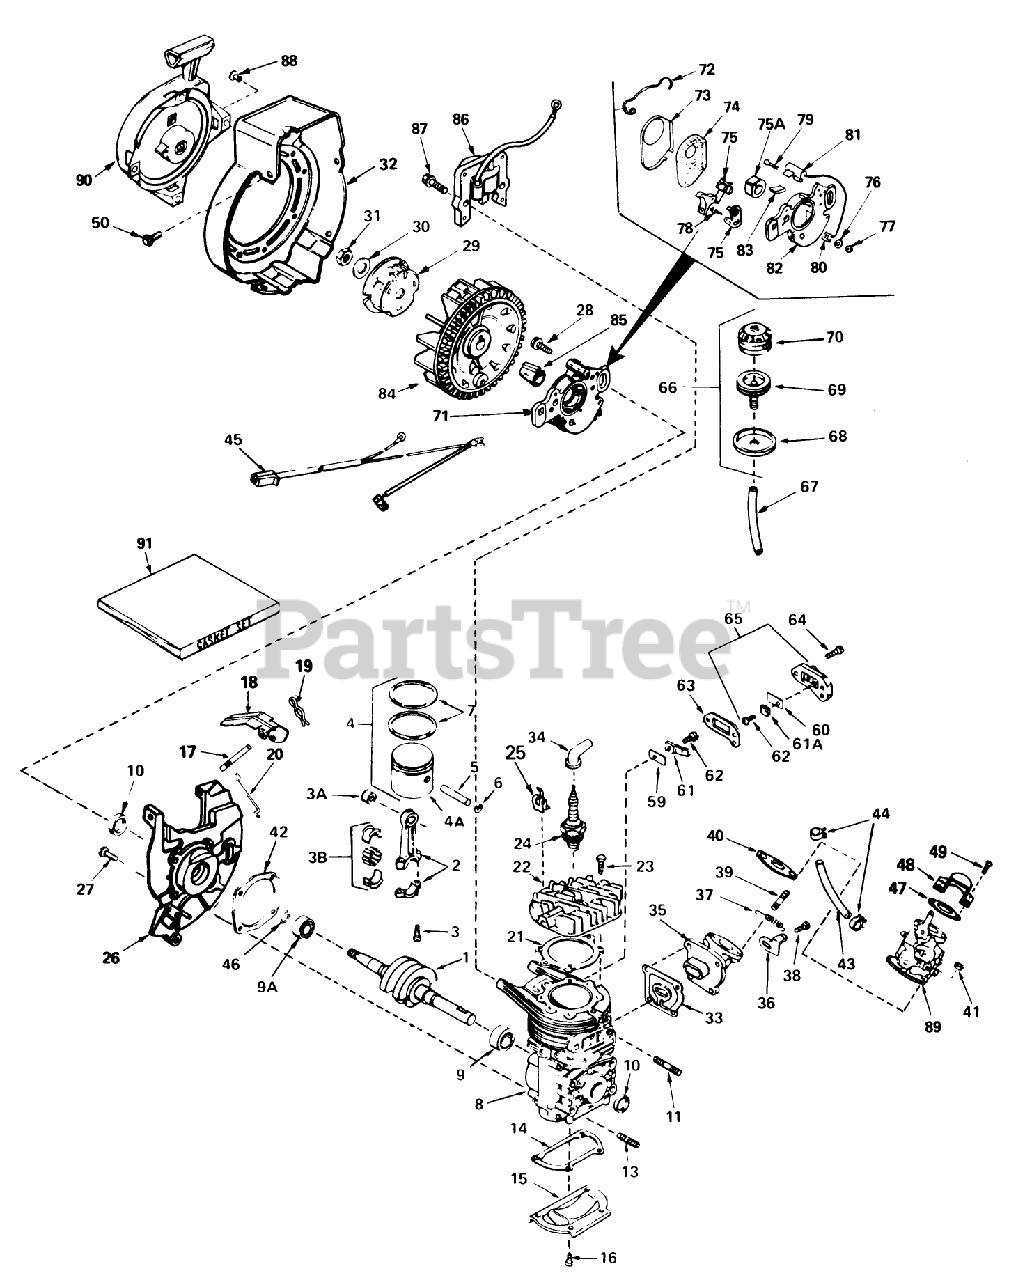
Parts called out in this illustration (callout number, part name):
1	Crankshaft
2	Rod Assembly, Connecting (Incl. #3, 3A 3B)
3	Bolt-Rod, Connecting
3A	Bearing-Cartridge
3B	Bearing Liner Set Needle
4	Piston, Pin Ring Assy. (Incl. Ref. #6 thru 9)
4A	Piston
5	Pin, Piston
6	Ring-Retaning
7	Ring Set
8	Block Assy., Cylinder (Order short block if replacement is required)
9	Bearing-Cartridge
9A	Bearing-Ball
10	Seal-Oil
14	Gasket, Cover
15	Plate, Cover
16	Screw (T-25, 10-24 x 1/2)
17	Shaft, Air Vane
18	Vane Assy., Air
19	Clip,Air Vane
20	Link-Governor
21	Gasket, Head
22	Head-Cylinder
23	Screw (T-30, 1/4-20 x 3/4)
24	Head Adjustment Knob
26	Base Assy., Blower Housing (Incl. Ref. #10 17)
26	Base Assy., Blowerr Housing (Incl. Ref. #10 17)(used on type 1603, 1603A 1603B)
27	Screw
28	Screw, Hex Washer Hd.
29	Cup-Starter
30	Washer-Spring
31	Nut-Flywheel
32	Housing-Blower
33	Gasket, Port
34	Cover-Spark Plug
35	Elbow Assy., Adapter
36	Lever, Adjusting
37	Spring, Adjusting Lever
38	Screw
39	Stud Carburetor
40	Gasket, Carburetor
41	Locknut
42	Gasket, Shroud Base
43	Line-Fuel
44	Clamp-Line, Fuel
45	Harness, Wire
46	Ring, Retaining
47	Gasket
48	Baffle-Carburetor
49	Screw
50	Screw-Hex, Hd.
59	Reed, Compression Release
60	Reed, Compression Release
61	Plate, Reed Hold Down
61A	Plate, Reed Hold Down
62	Screw
63	Gasket, Compression Release
64	Screw
65	Cover Assy., Compression release (Incl. Nos. 60, 61A 62)
66	Primer Assy.
67	Line, Primer
68	Retainer, Primer Bulb
69	Body, Primer
70	Bulb-Primer
71	Stator Plate Assy. (incl. Nos. 107, 111 thru 118 120)
72	Spring Breaker Box
73	Cover-Dust
74	Gasket Dust
75	Breaker Assy.
75A	Cam, Breaker
76	Washer
77	DECAL
78	Breaker Screw
79	Condenser Screw
80	Terminal, Ground
81	Condenser
82	Stator Plate
83	Felt,Cam Wiper
84	FIywheel
85	SHIELD
86	Lamination Coil Assy. (Incl. No. 42)
87	Screw
88	Rivet, Pop (3/16" dia .)(Can be purchased locally)
89	Carburetor (Incl. Ref. #40)
90	Starter-Rewind
91	Gasket Set (Incl. items marked *)
